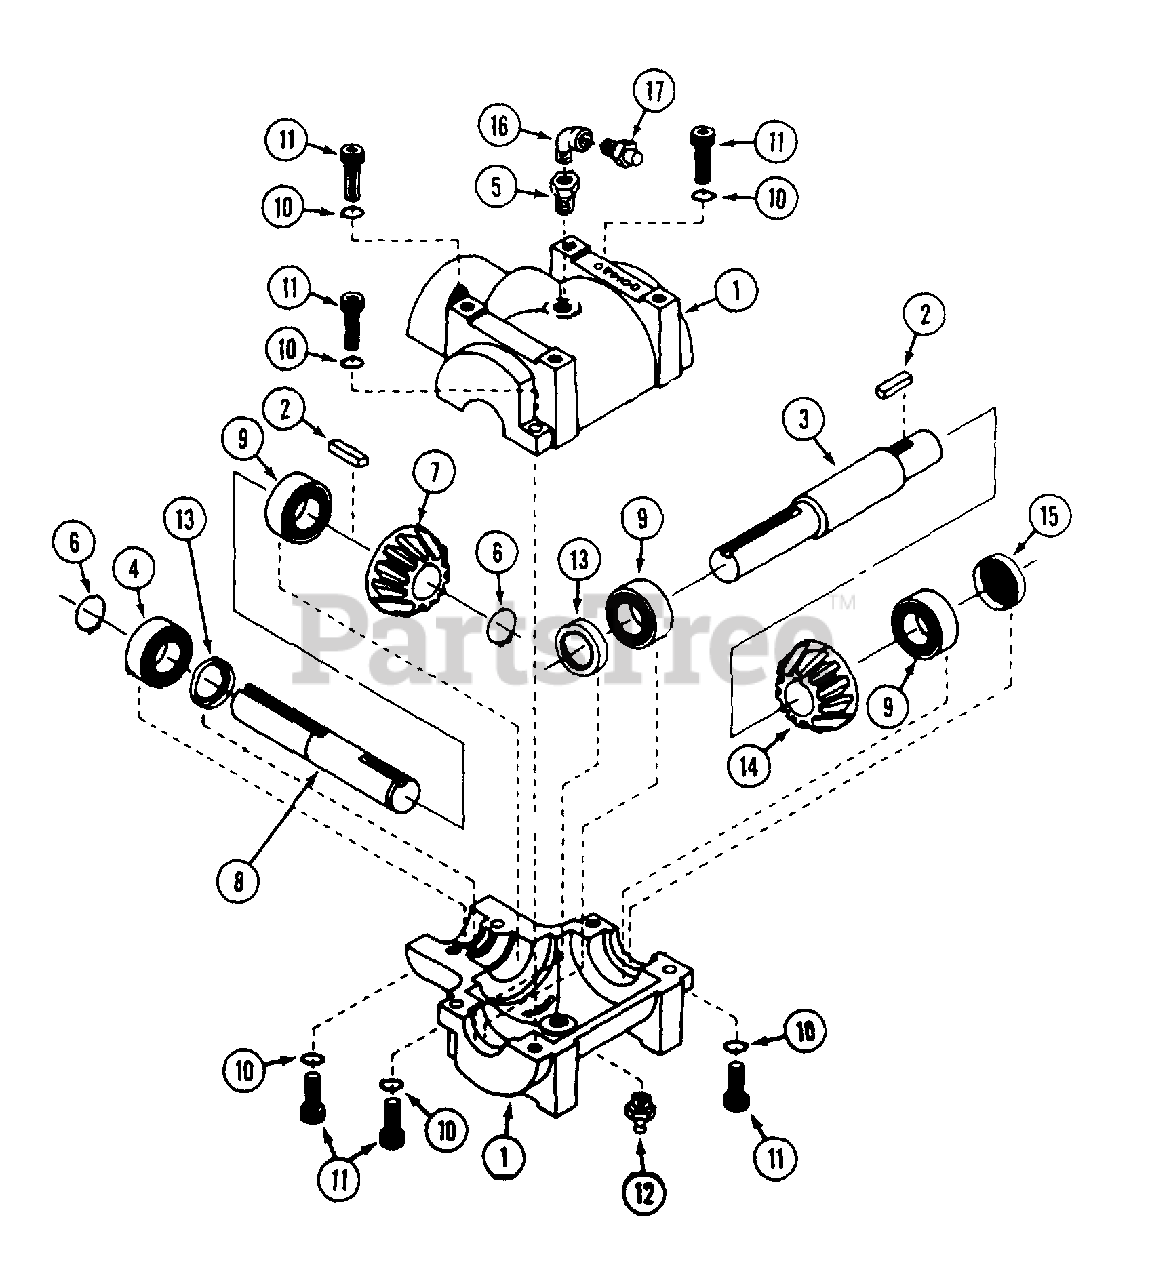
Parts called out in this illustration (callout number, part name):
1	HOUSING - half
2	KEY - 3/16" x 3/16" x 1"
3	SHAFT - input
4	BEARING - ball
5	BUSHING - pipe 1/4" x 118"
6	RING - retaining
7	GEAR - output shaft
8	SHAFT - output
9	BEARING - ball
10	LOCKWASHER
11	CAP SCREW - allen head
12	FITTING - grease 1/4" NPT
14	GEAR - input shaft
15	PLUG - expansion
16	ELBOW - street 1/8" x 90°.
17	VALVE - relief
